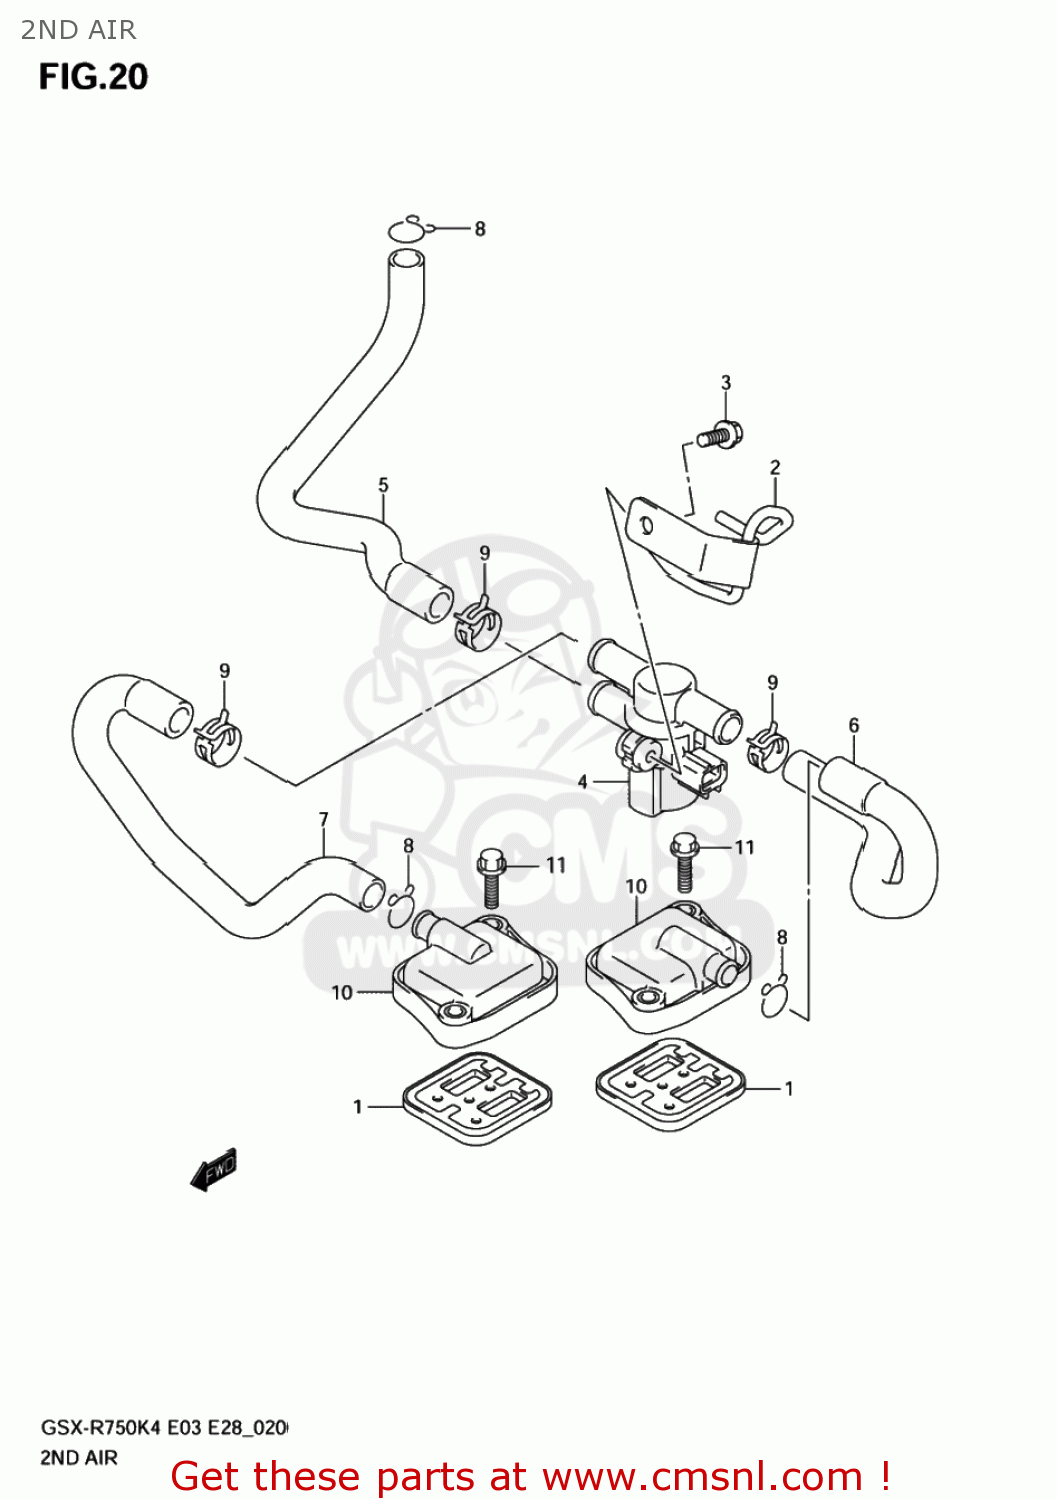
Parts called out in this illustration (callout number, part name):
1	VALVE ASSY,2ND
2	BRACKET,2ND AIR VALVE
3	BOLT
4	VALVE ASSY,AIR CUT
5	HOSE,2ND AIR CLEANER
6	HOSE,AIR CUT VALVE,L
7	HOSE,AIR CUT VALVE,R
8	CLIP
9	CLIP
10	COVER,2ND AIR REED VALVE
11	BOLT(6X20)
